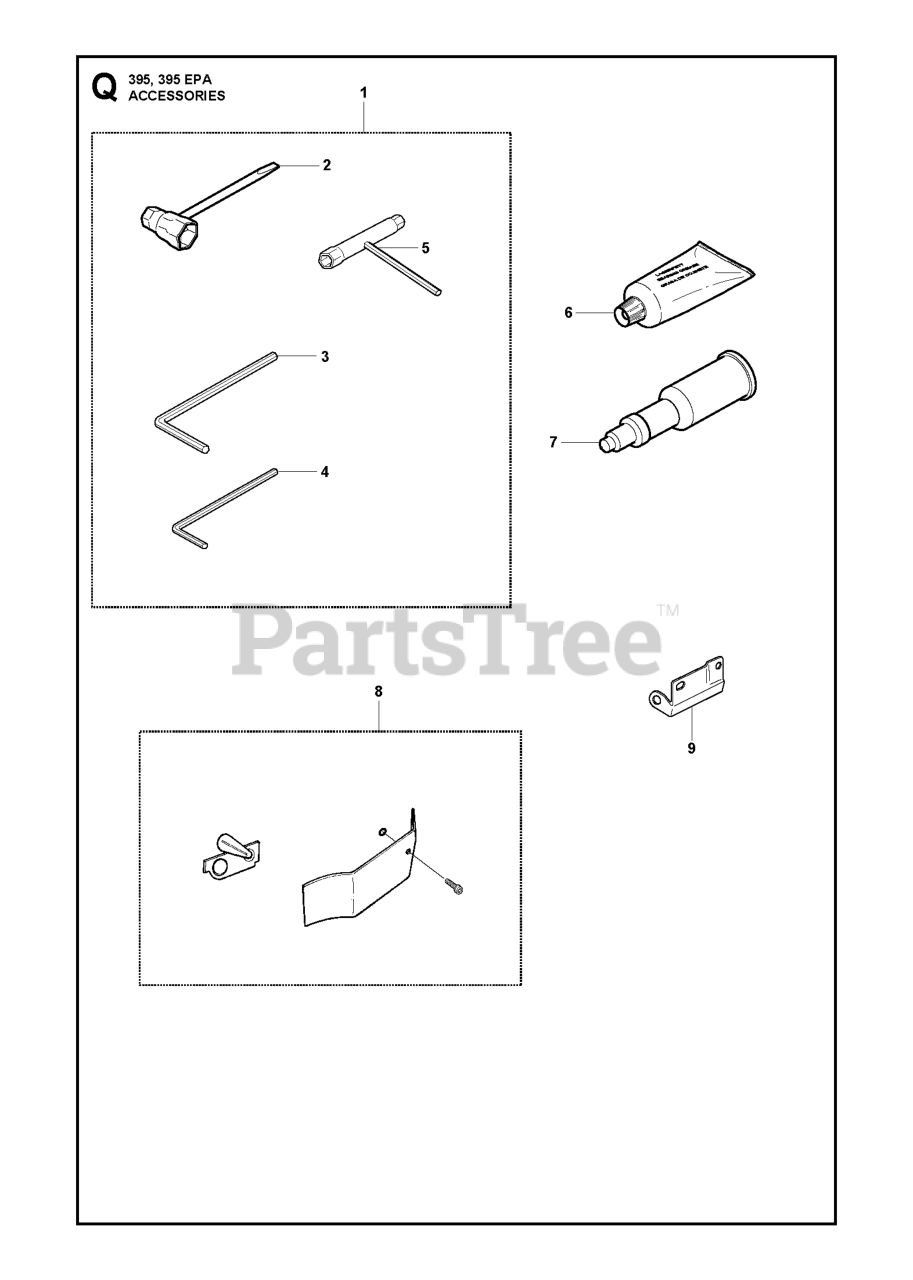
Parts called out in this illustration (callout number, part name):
2	COMBI TOOL
5	COMB.TOOL 8-10-14
6	GREASE
7	Grease Gun
8	WINTER KIT
